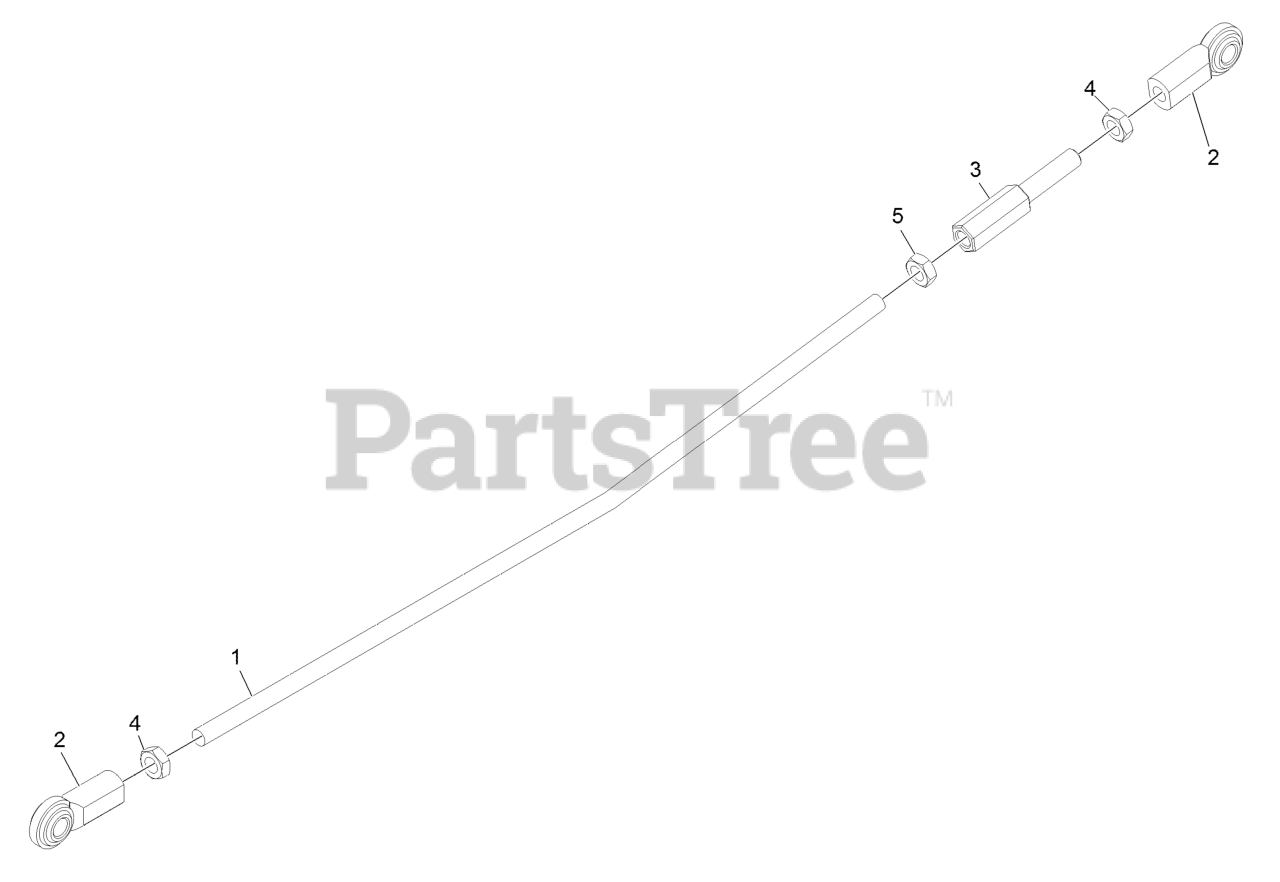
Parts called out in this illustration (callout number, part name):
1	LINK-LOWER, MOTION CONTRO
2	JOINT-BALL, END
3	ROD-ADJUSTMENT
4	NUT-HJ
5	NUT-HEX JAM, LH
